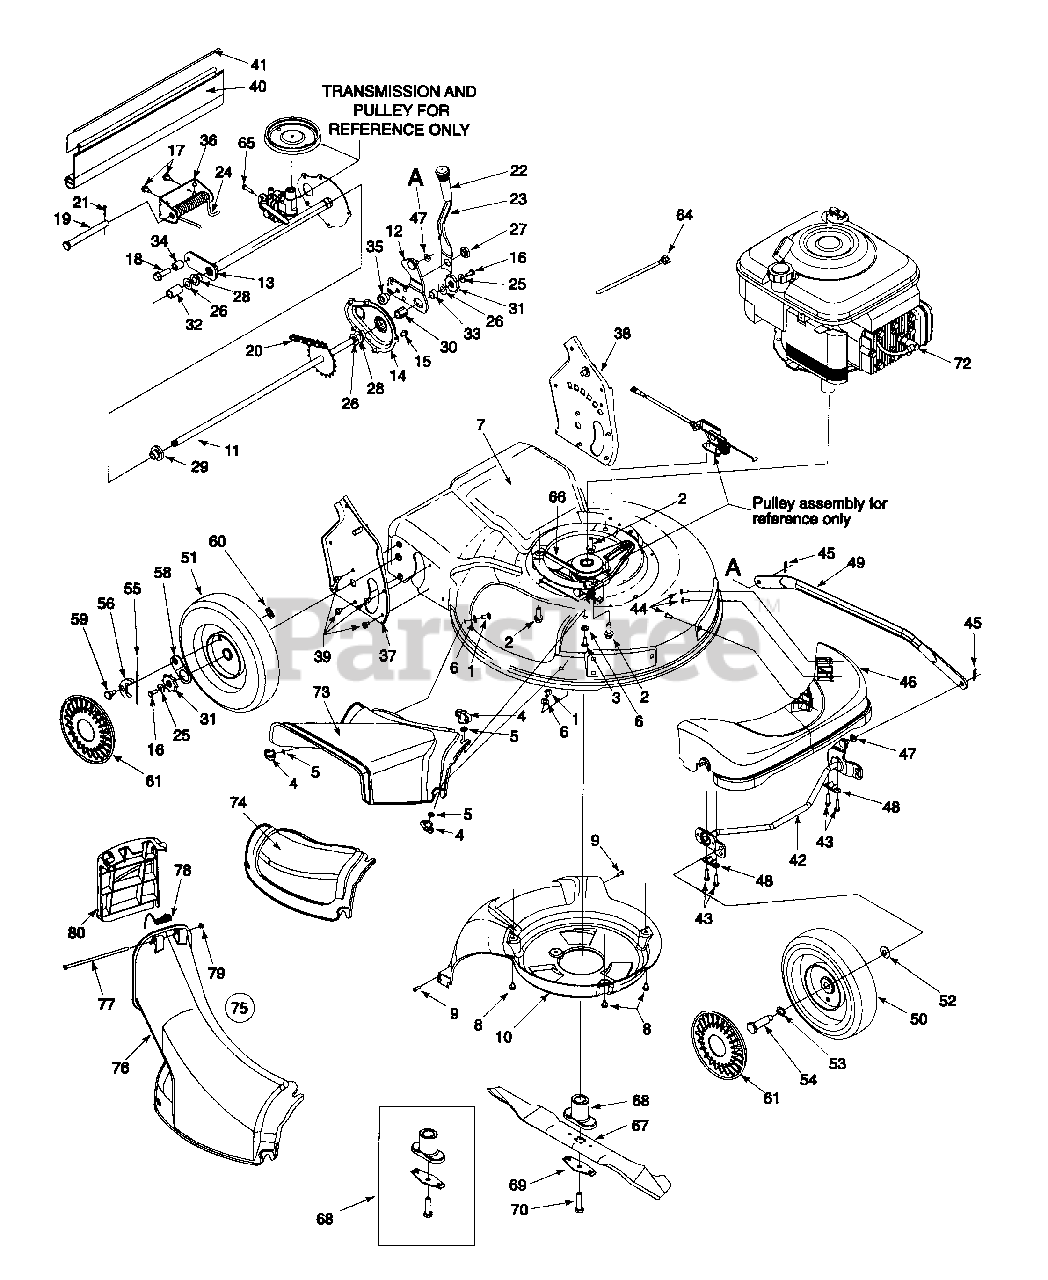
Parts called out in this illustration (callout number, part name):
1	Scr. Carr. 1/4-20 x .62
2	Scr. TT:3/8-18:1.00
3	Scr. 1/4-20 x .750
4	Wing Nut 1/4-20
5	Nut, Push .25 I.D. x .50 O.D.
6	Wash. Fl, .334 I.D. x .62 x .03
9	Scr. HL. 1/2-14 x .750
10	Baffle
11	Rear Axle Ass'y
16	Cap Screw HH 1/4-20 x .620
17	Scr. AB 1/4-14 x .825
18	Scr. 3/8 116 x .25
19	Clevis Pin .50 Dia. x 4.82 Lg.
20	Chain-Endls. #48 .500P x 24L
21	Cotter Pin .125 O.D. x .75
23	Spring Lever
24	Torsion Spring
25	Bell Wash. .285 x .75 x .082
26	Fl. Wash. .508 I.D. 1.000 x .
27	Nut Shld. .825 Dia. x .165 Lg.
28	Hx. Flg. Brg. .506 I.D. x .590 L.
29	Hx. Flg. Brg. .506 I.D. x .715 L.
30	Hx. Slv. Brg. .504 I.D. x .830 L.
31	Wheel Rachet
32	Spa. .550 I.D. x /750 O.D.
33	Spa. .51 .D. x .70 O.D. x 38 L.
34	Spa. .385 x .624 x .700
35	Shld. Spa. .385 I.D. X .715 Lg.
40	Trail Shield
41	Trail Shield Wire
43	Hx Scr. Wash Hd. Hi.-Lo.
44	Scr. Torx, Truss Hi.-Lo.
45	Cotter Pin .072 x 1.12 Lg.
46	Fr. Axle Cover, Yellow
47	Bowed Washer
48	Bush. Block .505 Dia. x .62
50	Wheel 8 x 2 Link, Yellow
51	Wheel 9 x 2 Link Yellow, Slv.
52	Spr. Wash. .401 x .870 x .063
53	Wave Wash .510 x .750 x .017
54	Shldr Scr .498 x 1.445 x 3/8-16
55	Spring, Ratchet, Plastic
56	Pawl - R.H.
56	Pawl - L.H.
58	Ratchet Pawl Plate
59	Scr. Shld. .340 x .285
60	Top Lock Tab Weld Nut 1/4-20
61	Hubcap - Yellow
62	Screw .620 Hx. Slt. Wsh.
63	Casing Clamp, Throttle
64	Cable Tie
65	Hex Scr. 5/16-18
66	V-Belt
67	21" Mulching Blade
68	Blade Adapter Kit
69	Blade Bell Support
70	Hex Bolt 3/8-24 x 2.5" Lg.
72	Spark Plug Insulator
73	Side Discharge Chute
74	Mulch Cover
75	Chute Ass'y
76	Discharge Chute
77	Pivot Rod
78	Torsion Spring
79	Push Cap
80	Chute Door
